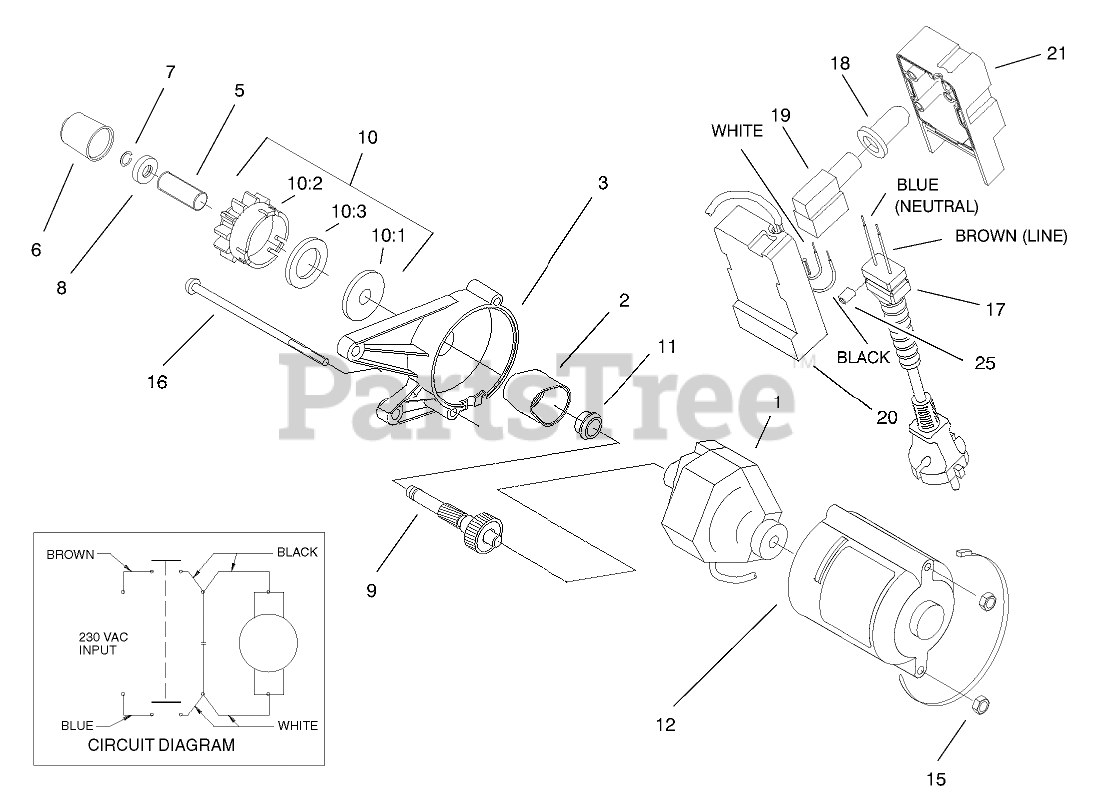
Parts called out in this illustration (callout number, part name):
1	MOTOR-STARTER
2	COVER-GEAR
3	HOUSING-UPPER, STARTER
5	SPRING
6	CAP-PINION
7	RING-LOCK
8	STOP-PINION
9	SHAFT/GEAR ASM
10	PINION ASM
10:2	PINION
10:3	RING-RUBBER
11	BUSHING
12	HOUSING-LOWER, STARTER
15	NUT-LOCK, NI
17	PLUG-POWER 230 VOLT
18	BOOT-SWITCH
19	SWITCH-STARTER
20	SWITCH-BASE, HOUSING
21	HOUSING-CAP, SWITCH
25	SPACER-PLUG
